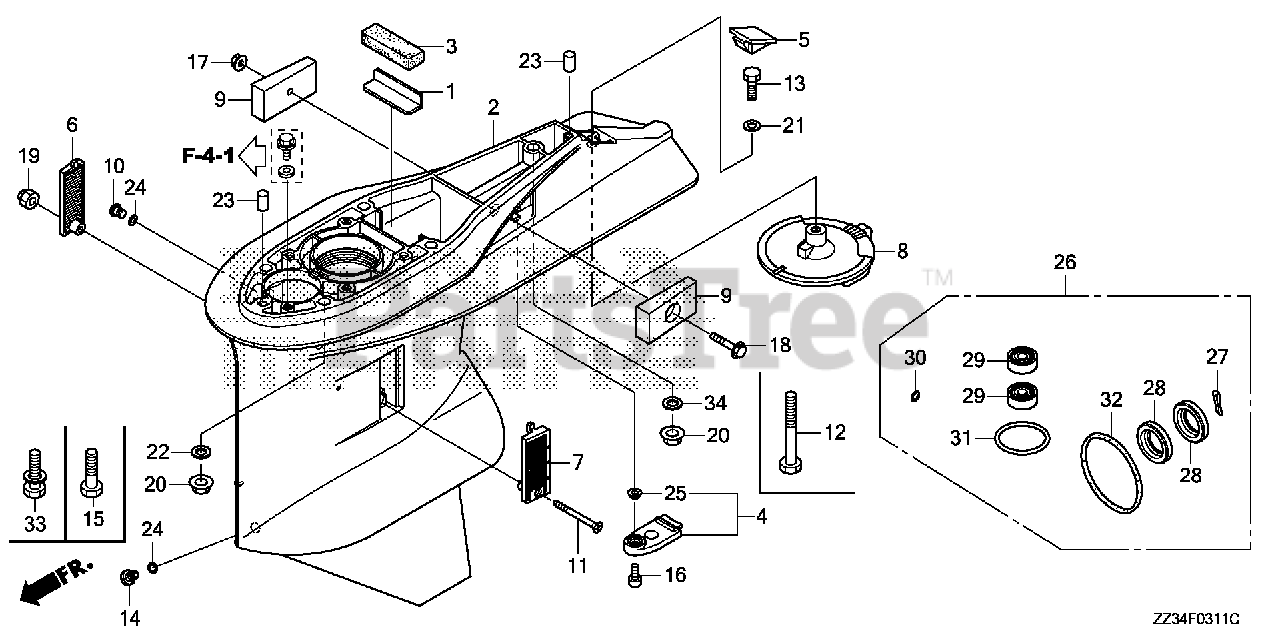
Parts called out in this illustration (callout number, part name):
1	PLATE, RUBBER SETTING
2	CASE, GEAR *NH282MU* (OYSTER SILVER METALLIC-U)
3	GROMMET, GEAR CASE
4	COVER B, GEAR CASE
5	GROMMET, GEAR CASE
6	SCREEN, R. WATER
7	SCREEN, L. WATER
8	TAB, TRIM *NH282MU* (OYSTER SILVER METALLIC-U)
9	METAL, ANODE
10	BOLT, OIL CHECK
11	SCREW, FLAT (5X55)
13	BOLT, HEX. (8X25)
14	BOLT, DRAIN PLUG
16	BOLT, SOCKET (6X16)
17	NUT, SELF-LOCK (6MM)
18	BOLT, FLANGE (6X35)
19	NUT, SELF-LOCK (5MM)
20	NUT, SELF-LOCK (10MM)
21	WASHER, PLAIN (8MM)
22	WASHER, PLAIN (10MM)
23	PIN, DOWEL (6X10)
24	O-RING (6.9X1.45)
25	COLLAR, DISTANCE (6.5X9X3)
26	CASE KIT, GEAR (P/T)
27	PIN, SPLIT (4.0)
28	SEAL, WATER (30X45X7)
29	SEAL, WATER (12X21X6)
30	O-RING (6.9X1.45)
31	O-RING
32	O-RING (94X4.1)
34	WASHER, PLAIN (10MM)
